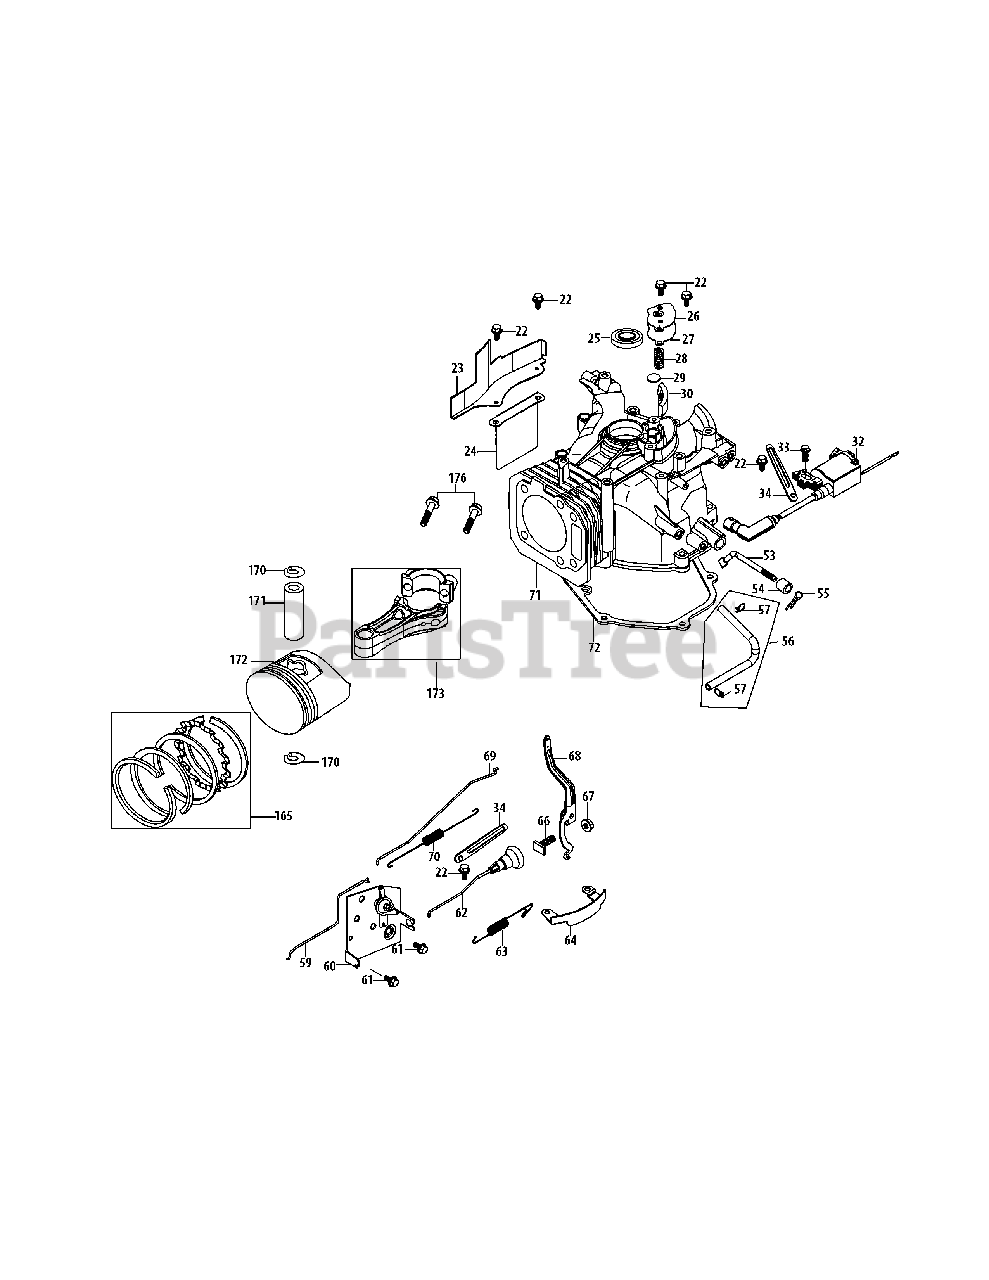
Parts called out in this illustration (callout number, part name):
22	Bolt M6×14
23	Air Guide Bracket
24	Label Bracket
25	Upper Crankshaft Seal
26	Breather Cover Plate
27	Breather Gasket
28	Breather Spring
29	Breather Valve
30	Mesh Screen
32	Ignition Coil Assembly
33	Bolt M6×18
34	Flexible Clamp
53	Governor Arm Shaft
54	Governor Seal
55	Cotter Pin
56	Breather Hose Assembly
57	Breather Hose Clamp
59	Choke Linkage
60	Variable Speed Control Brkt
61	Bolt M6×12
62	Choke Control Knob
63	Governor Spring
64	Governor Arm Shield
66	Governor Arm Bolt
67	Nut M6
68	Governor Arm
69	Throttle Linkage
70	Throttle Linkage Spring
71	Short Block Assembly
72	Crankcase Cover Gasket
165	Piston Ring Set
170	Piston Pin Snap Ring
171	Piston Pin
172	Piston
173	Connecting Rod Assembly
176	Connecting Rod Bolt
